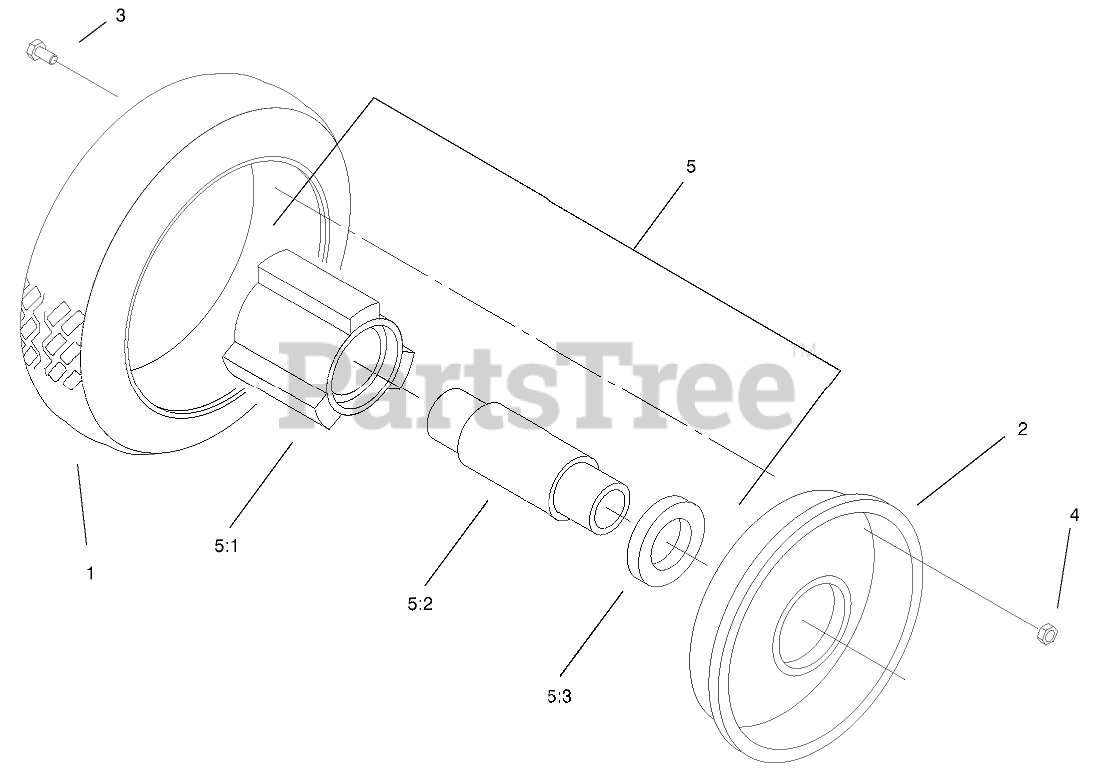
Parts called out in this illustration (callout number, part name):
2	PLATE-WHEEL, HALF
3	SCREW-HH
4	NUT-LOCK, NI
5	Hub & Brg ASM
5:1	HUB-BEARING
5:2	SPACER-BEARING
5:3	BEARING-WHEEL
